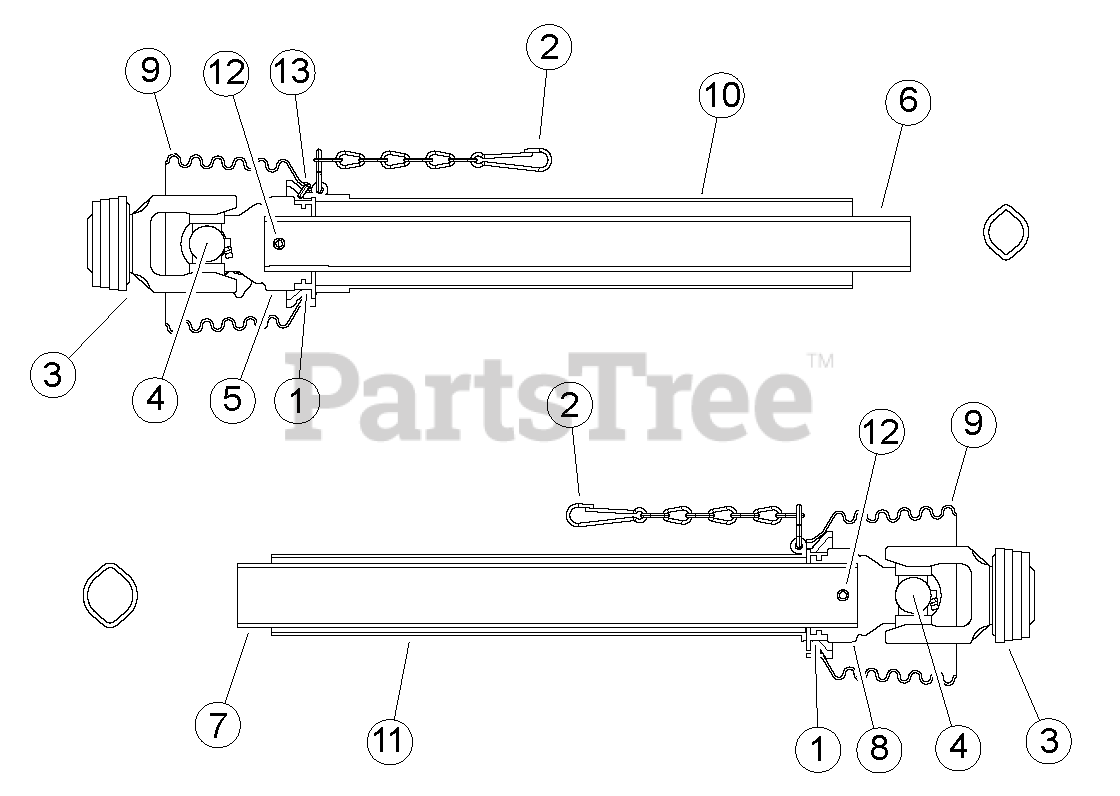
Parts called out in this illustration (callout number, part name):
1	RING, SC15 BEARING
2	CHAIN, SAFETY
3	YOKE, 1-3/8-6 SPLINGE ASGE
4	KIT, CROSS & BEARING
5	YOKE, INBOARD 0V
6	PROFILE, INNER 0V
7	PROFILE, OUTER 1
8	YOKE, INBOARD 1
9	CONE, 4 RIB
10	GUARD, TUBE OUTER
11	GUARD, TUBE INNER
12	PIN, 10 X 65 SPRING
13	SCREW, WS365344
